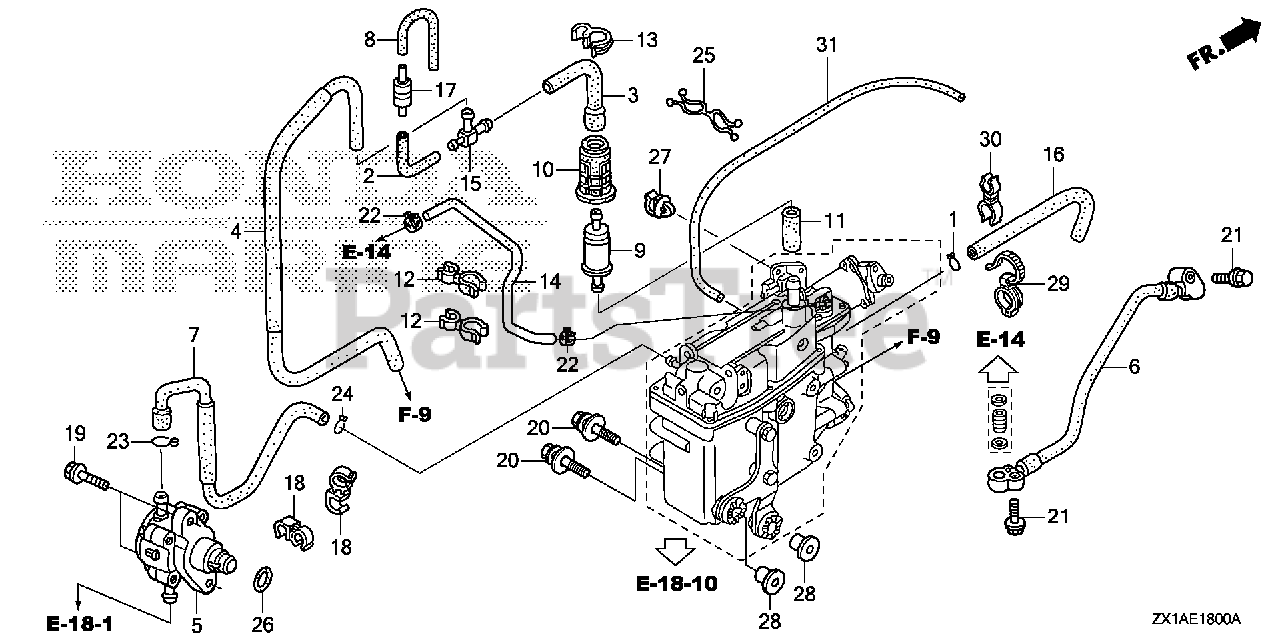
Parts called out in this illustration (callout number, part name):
1	CLIP, TUBE (ENGINE NO.)
2	TUBE C, AIR VENT
3	TUBE B, AIR VENT
4	TUBE, AIR VENT
5	PUMP ASSY., FUEL (MSDS)
6	HOSE, FUEL
7	TUBE B, FUEL
8	TUBE D, FUEL
9	FILTER, FUEL PUMP
10	SUSPENSION, STRAINER
11	TUBE B, FUEL
12	CLAMP, HOSE
13	CLAMP, PIPE
14	HOSE, PRESSURE REGULATOR RETURN
16	TUBE G, WATER
17	VALVE, CHECK
18	CLIP, SENSOR HOSE
19	BOLT, FLANGE (6X27)
20	BOLT-WASHER (8X35)
21	BOLT, FLANGE (6X25)
22	CLAMP, TUBE (D10.7)
23	CLIP, TUBE (B1 14.5)
24	CLIP, TUBE (B12)
25	CLIP, FUEL HOSE
26	O-RING (33.2X2.4) (NOK)
27	CLIP, HARNESS
28	COLLAR (8.5X14.5)
29	CLIP, TUBE (135MM) (BLACK)
30	CLAMP, PURGE HOSE (NOT AVAILABLE)
31	BULK HOSE, FUEL (3.5X3000) (3.5X120)
